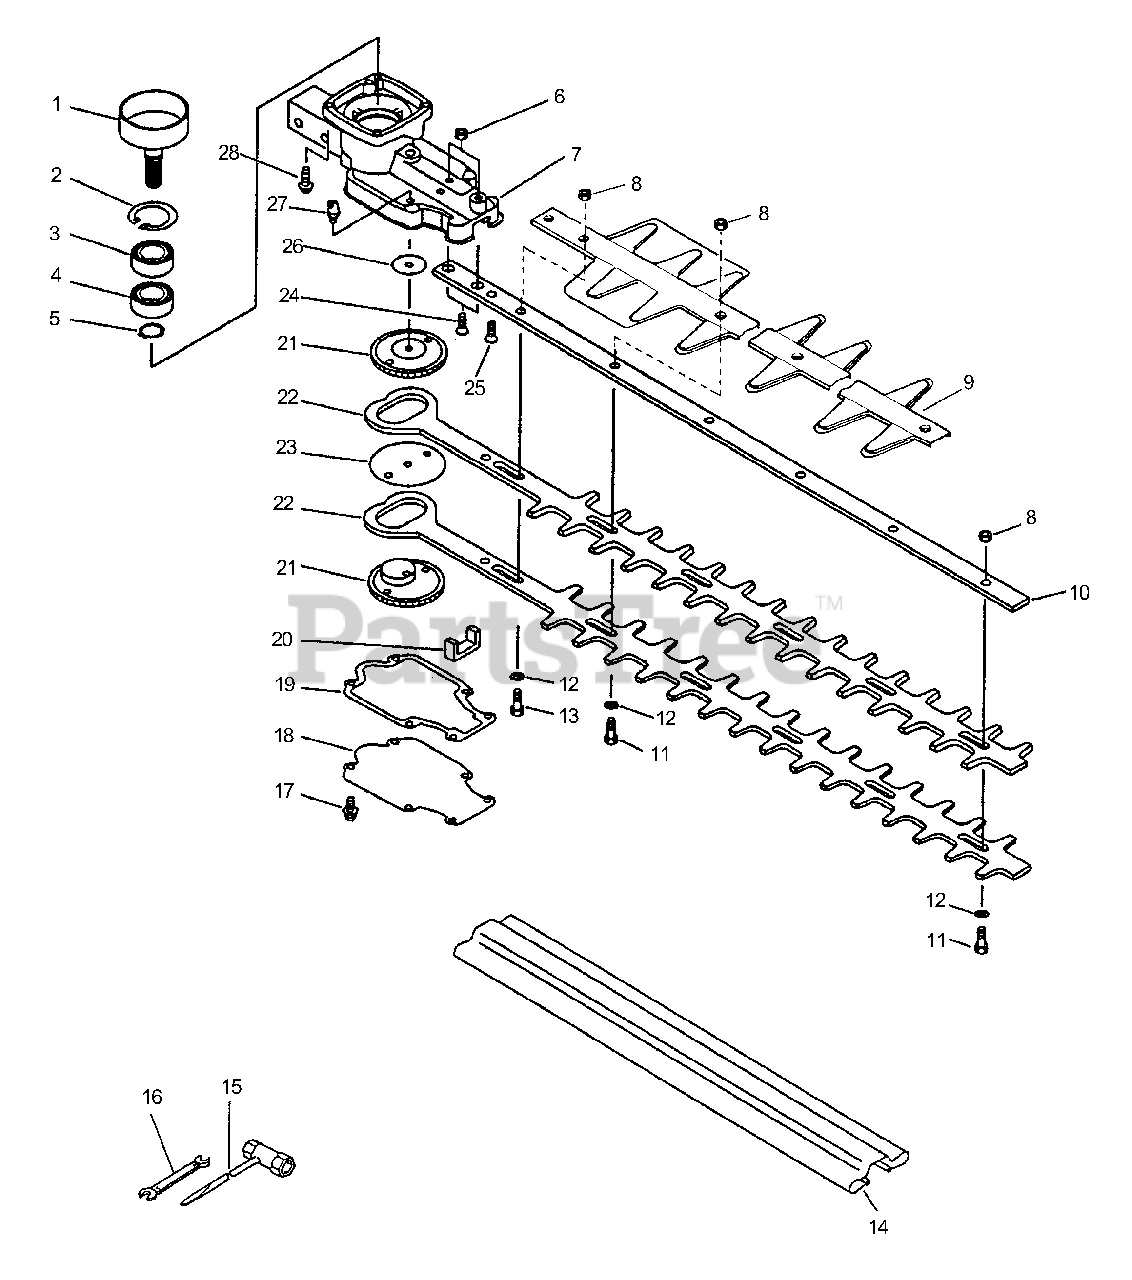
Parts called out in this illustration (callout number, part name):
1	DRUM, CLUTCH
2	RING, RETAINING - 35
3	BEARING, BALL - 6202
4	BEARING, BALL - 6202
5	RING, RETAINING - 14
6	LOCKNUT - 6
7	CASE, GEAR
8	LOCKNUT - 6
9	SUPPORT, BLADE
10	SUPPORT, BLADE
11	BOLT - 6X18
12	WASHER - 6
13	BOLT - 6X35
14	COVER, BLADE
15	T-WRENCH - 13X19mm
16	SPANNER - 8X10mm
17	SCREW - 4X12
18	LID, GEAR CASE
19	GASKET, GEAR CASE
20	SEAL, FELT
21	GEAR - SPUR
22	BLADE
24	SCREW - 6X30
25	SCREW - 5X30
27	FITTING, GREASE
28	SCREW - 4X16
